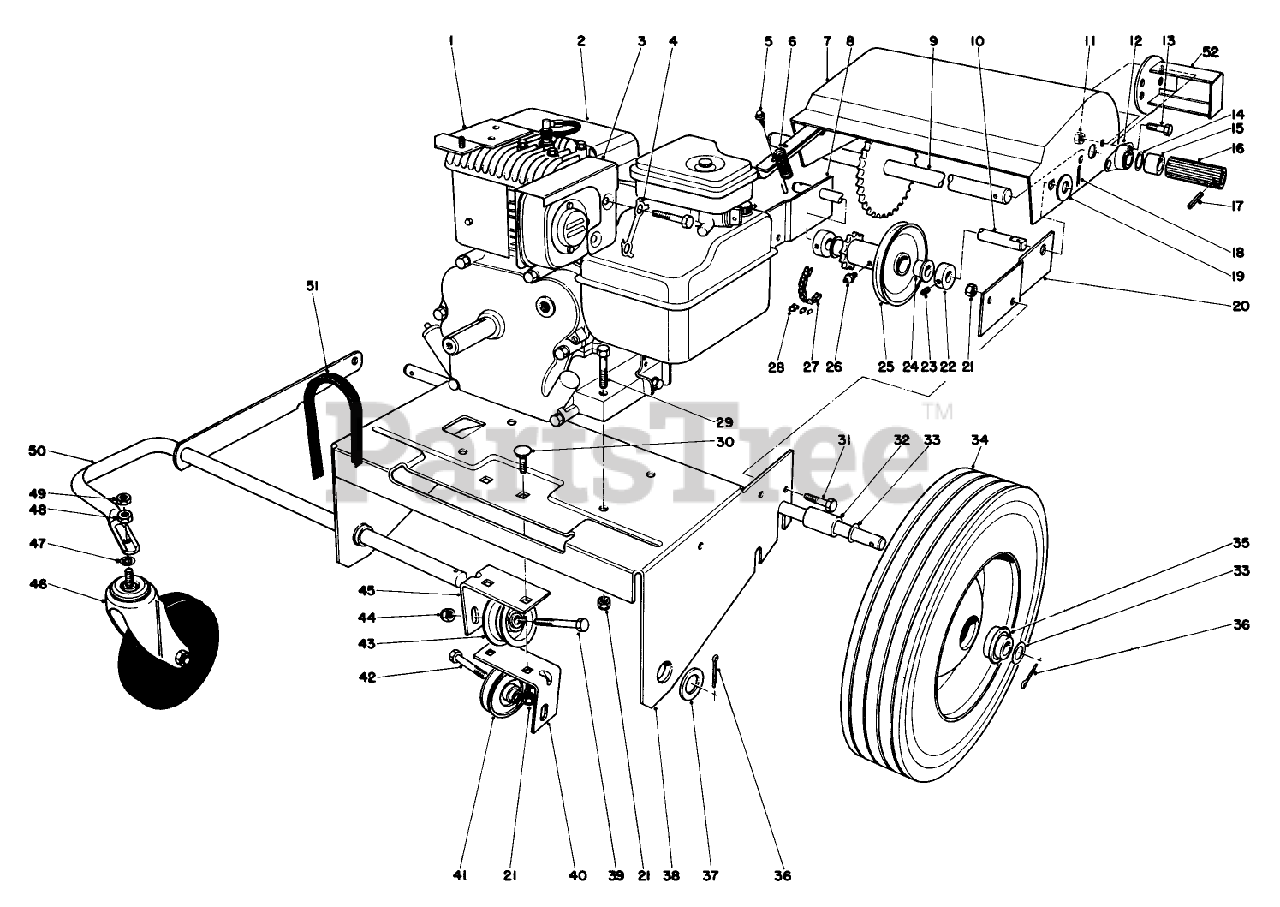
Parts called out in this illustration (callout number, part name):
1	MTG BRKT WA B
2	Engine
3	HEAT SHIELD
4	Lock Strip
5	SCREW-HH
6	SPRING-TRACTION
7	GUARD WA
8	Mounting Bracket
9	SHAFT-WHEEL, FRICTION
10	SHAFT-IDLER
11	NUT-LOCK, NI
12	BEARING-MOUNT, FLANGE
13	SCREW-HH
14	WASHER
15	SPACER
16	WHEEL-FRICTION
17	PIN-ROLL, SLOTTED
18	PIN-COTTER
19	WASHER-FLAT
20	Mounting Bracket
21	NUT-LOCK, CONE
22	Set Screw Collar (Inc. Ref. #23)
23	SCREW-SET, HSH
24	BUSHING-FLANGE
25	Idler Assembly (Incl. Ref. #24 & 26)
26	FITTING-GREASE
27	Traction Chain (Incl. Ref. #28)
28	LINK-CONNECTING, NO. 35
29	SCREW-HH
30	SCREW-CARR
31	SCREW-HH
32	SPACER-AXLE
33	WASHER
34	Wheel (Incl. Ref. #35)
35	BEARING
36	PIN-COTTER
37	WASHER-FLAT
38	Engine Plate
39	SCREW-HH
40	Bracket-Idler Mount L.H.
41	PULLEY-IDLER
42	SCREW-HH
43	PULLEY-IDLER
44	NUT-LOCK, CONE
45	Bracket-Idler Mount R.H.
46	CASTER
47	Lockwasher
48	NUT-HH
49	1/2-13 CONELOCK NUT
50	Front Wheel Support
51	BELT-V
52	Guard
